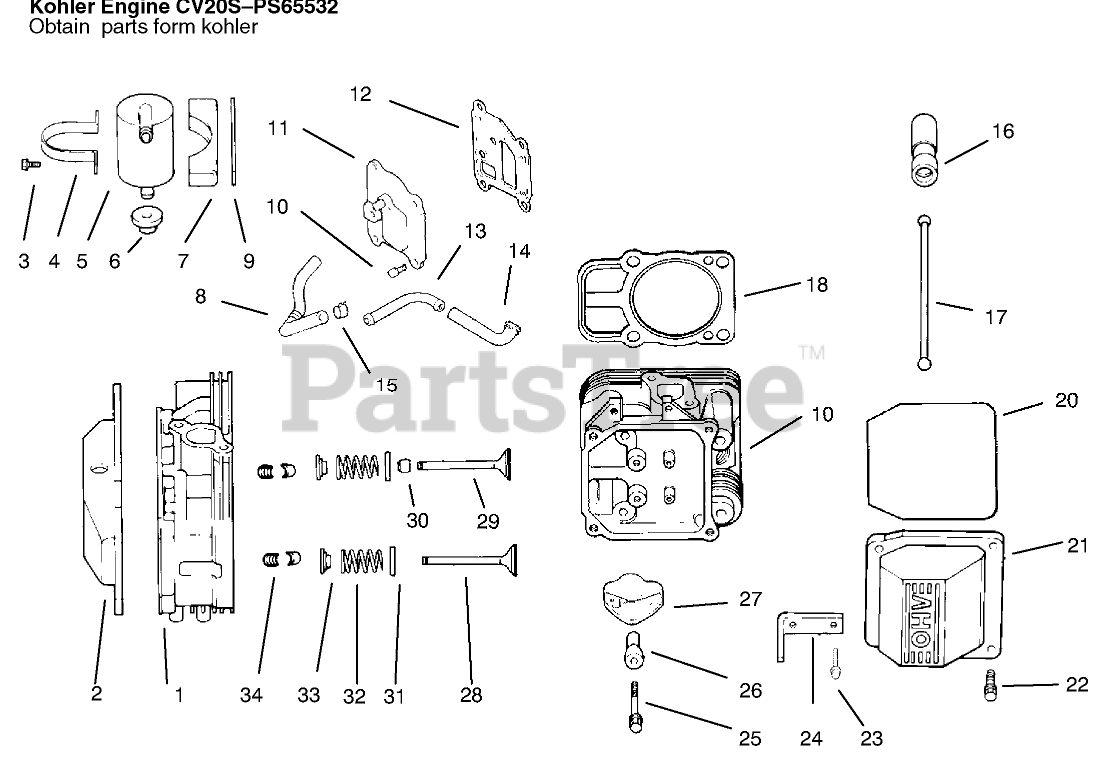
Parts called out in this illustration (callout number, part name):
1	#1 Cyl. Head Asm
2	Cover-Rocker
3	Kit-Breather INC 4
4	Grommet-Rubber
5	Cover-Breather
6	Screw
7	Hose-Breather
8	Retainer Kit
9	Cap-Spring, Valve
10	Spring-Valve
11	Retainer-Spring
12	Valve-Exhaust
13	Valve-Intake
14	Seal-Stem, Valve
15	Fitting
16	Hose-Breather
17	Lifter-Valve
18	Rod-Push
19	Gasket-Cylinder Head
20	#2 Cyl. Head Asm,
21	Arm-Rocker
22	Pivot-Rocker Arm
24	Cover-Rocker
25	Screw
26	Screw
27	Strap-Lifting
